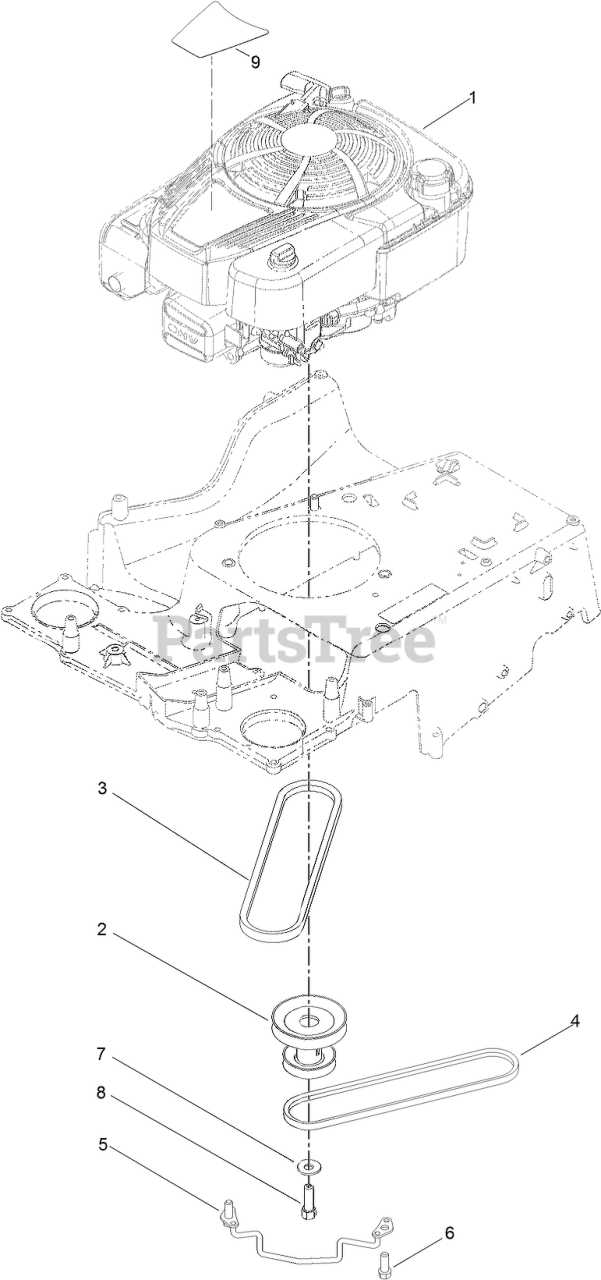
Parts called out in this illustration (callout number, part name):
2	PULLEY-ENGINE
3	V-BELT
4	V-BELT, TRACTION
5	GUIDE-BELT
6	SCREW-TAPTITE
7	WASHER-BELLEVILLE
8	SCREW-HH
9	DECAL-SHROUD
